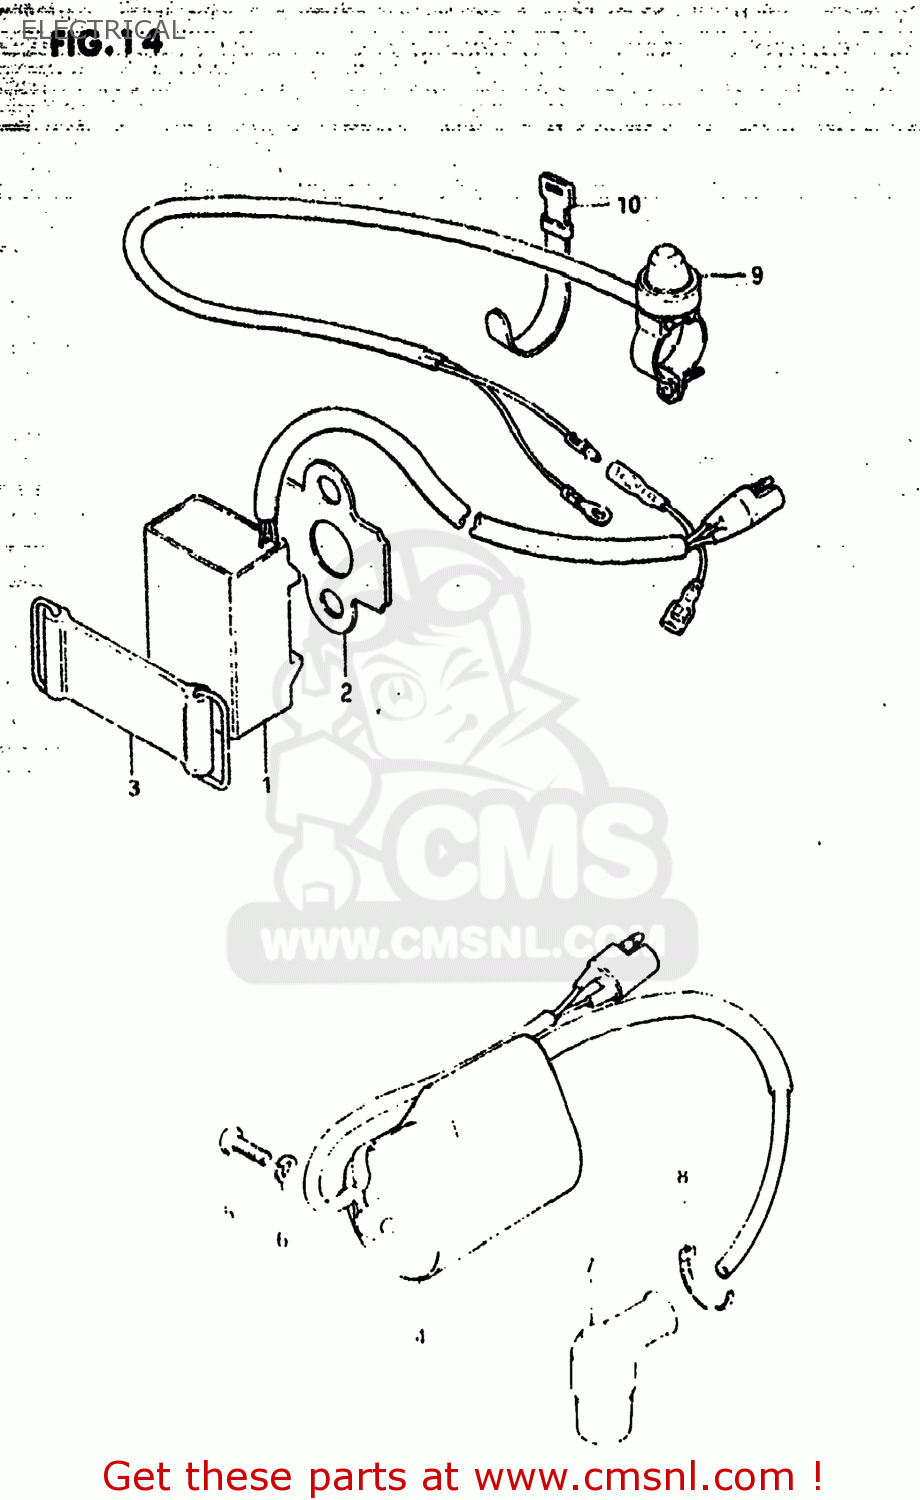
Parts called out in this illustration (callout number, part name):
1	CDI UNIT
2	PROTECTOR,CDI UNIT
3	BAND
4	COIL ASSY,IGNITION
5	SCREW 5X20
6	LOCK WASHER
7	CAP,SPARK PLUG
8	CLAMP
9	SWITCH ASSEMBLY
10	CLAMP(L:120)
